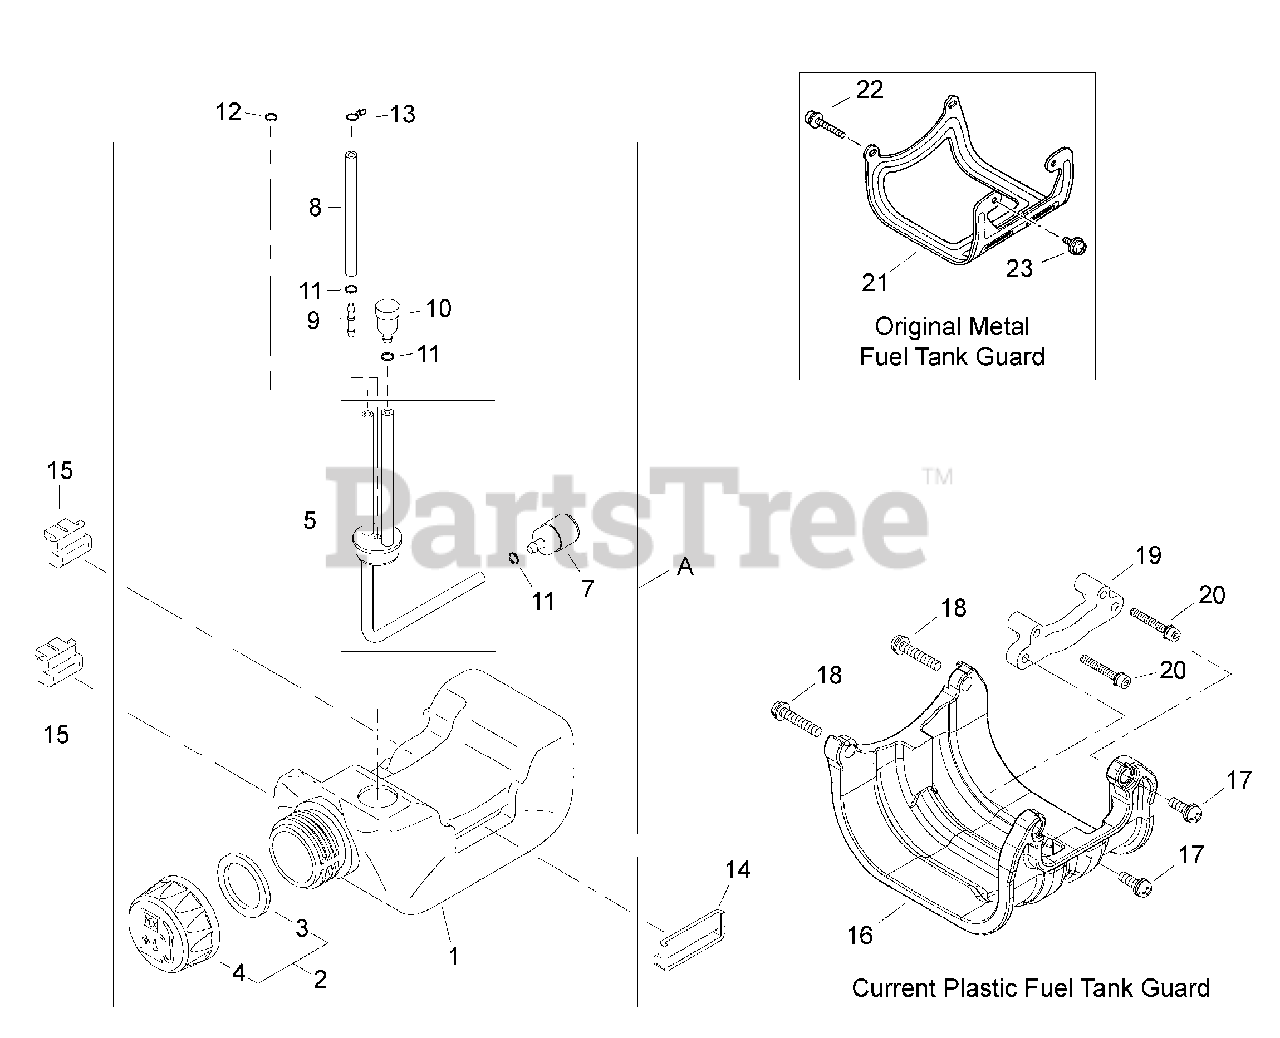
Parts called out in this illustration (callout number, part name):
1	TANK, FUEL
2	CAP ASSY, FUEL
3	GASKET, FUEL CAP
4	CAP, FUEL
5	GROMMET, FUEL W/VENT PIPE
7	FILTER, FUEL 125-528
8	PIPE, FUEL RETURN
8-A	TANK ASSY, FUEL
9	CONNECTOR, PIPE
10	VENT ASSY
11	CLIP Ø6
12	CLIP Ø6
13	CLIP, SPRING Ø5.2
14	CUSHION, FUEL TANK
15	CUSHION, FUEL TANK
16	GUARD, PLASTIC FUEL TANK
17	SCREW M5×18
18	SCREW M5×35
19	BRACKET
20	BOLT M4×30
21	GUARD, METAL FUEL TANK
22	SCREW M5×30
23	SCREW M5×12
